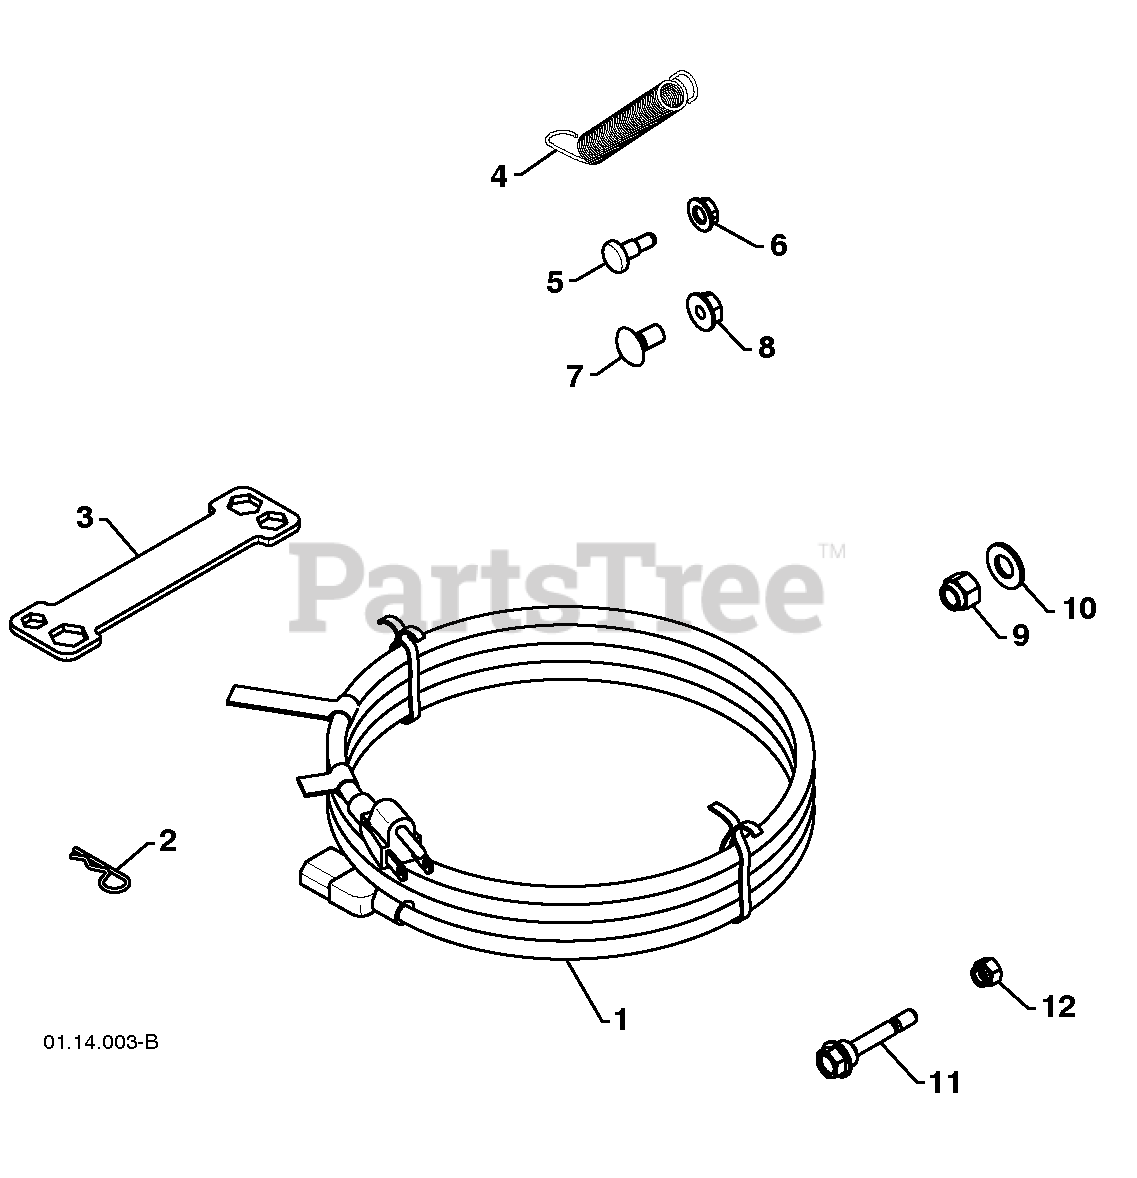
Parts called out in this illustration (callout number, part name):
1	POWER CORD
2	RETAINER PIN
3	WRENCH
4	REMOTE SPRING
5	SHOULDER BOLT 1/4-20
6	LOCKNUT 1/4-20
7	CARRIAGE BOLT 5/16-18 X 5/8
8	LOCKNUT 5/16-18
9	LOCKNUT 3/8-16
10	WASHER 3/8
11	SHEAR BOLT 1/4-20 X 1-13/16
12	LOCKNUT 1/4-20
